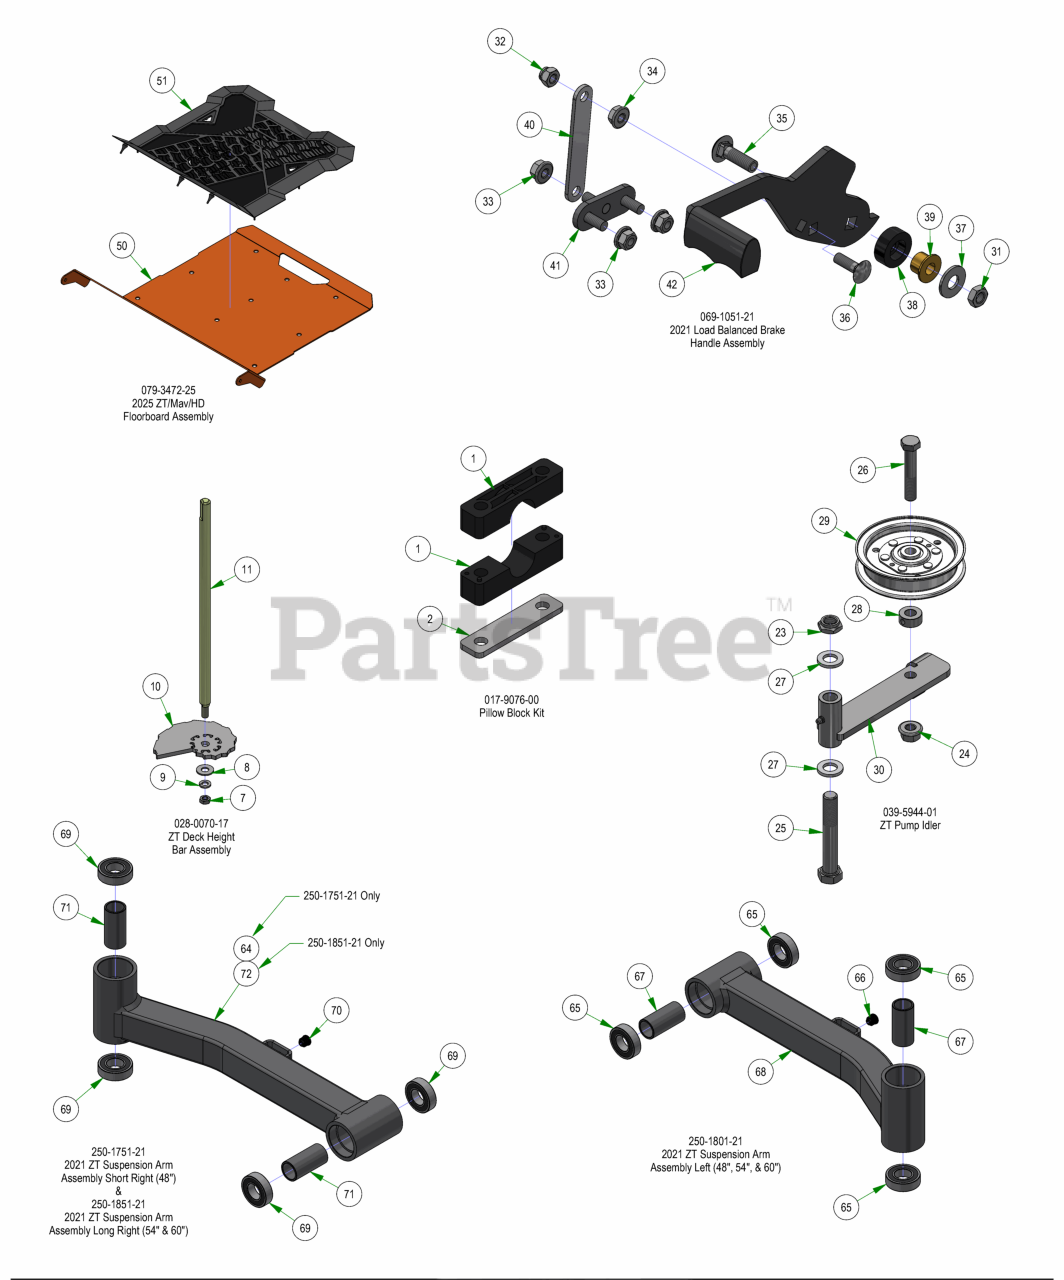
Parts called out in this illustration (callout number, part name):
1	Pillow Block MZ
2	Pillow Block Strap
3	5/16-18 NYLON INSERT FLANGE LOCKNUT ZINC
4	5/16-18 X 1 CARRIAGE BOLT (GR.8) ZINC
5	2017 MZ/ZT Shallow Foot Pedal
6	2017 MZ/ZT Deck Pedal Lever
7	3/8-24 HEX NUT ZINC YELLOW
8	3/8 FLAT WASHER USS (1" OD) ZINC
9	3/8 SPLIT LOCKWASHER ZINC
10	2017 MZ/ZT Cam Plate
11	2017 Deck Height Dial Rod ZT
12	3/8-16 Half Jam Nut
13	3/8-16 HEX SERRATED FLANGE NUT HARD/ZINC
14	3/8-16 X 2 HEX CAP SCREW (GR.5) ZINC
15	3/8 FLAT WASHER USS (1" OD) ZINC
16	Seat Spring
17	3/8-16 Half Jam Nut
18	3/8-16 HEX SERRATED FLANGE NUT HARD/ZINC
19	3/8-16 X 2 HEX CAP SCREW (GR.5) ZINC
20	3/8 FLAT WASHER USS (1" OD) ZINC
21	Seat Spring
22	Seat Strap with Buckles
23	5/8-11 NYLON INSERT JAM LOCKNUT ZINC
24	1/2-13 NYLON INSERT FLANGE LOCKNUT ZINC
25	5/8-11 X 4 HEX CAP SCREW (GR.8) ZINC YELLOW
26	1/2-13 X 2-3/4 HEX CAP SCREW (GR.5) ZINC
27	.635 ID X 1.120 OD X .140 THICK FLAT WASHER NYLON
28	1/2 SOLID SHAFT COLLAR (W/1 SET SCREW) ZINC
29	4 3/4" Idler Pulley
30	Pump Idler Bracket
31	3/8-16 HEX JAM 2-WAY REVERSIBLE CENTER LOCKNUT ZINC
32	5/16-18 NYLON INSERT CAP LOCKNUT ZINC (BLK CAP)
33	5/16-18 NYLON INSERT FLANGE LOCKNUT ZINC
34	5/16-18 HEX SERRATED FLANGE NUT HARD/ZINC
35	3/8-16 X 1-1/4 CARRIAGE BOLT ZINC
36	5/16-18 X 1 CARRIAGE BOLT (GR.8) ZINC
37	3/8 FLAT WASHER USS (1" OD) ZINC
38	2015 Brake Lever Spacer
39	.377 ID X .625 OD X .500 HGT X .880 FLNG DIA X .060 FLNG THK BUSHING
40	Brake Cable Extension Plate
41	Brake Load Balancer Lower Weldment
42	Load Balanced Brake Handle with Grip
43	Black Seat stop from Seat King
44	Seat Cover Molded Foam for 071-2040-18/071-5080-18
45	Back Cover for 071-2101-00
46	Seat Cover for 071-2101-00/071-2102-00
47	Arm rest Kit for 071-2102-00
48	Seat Rails for Outlaw Seat/2020 ZT Elite/ZTAvenger
49	13/14 MZ/Outlaw Seat Switch
50	2025 Elite Maverick Floorboard
51	25 Mav Floor Mat. V4
52	Ignition Switch
53	10-24 NYLON INSERT LOCKNUT ZINC
54	Light Plug
55	10-24 X 5/8 BUTTON SOCKET CAP SCREW 18-8 STAINLESS STEEL
56	Throttle Lever Assembly
57	PTO Engager
58	4-Way Key Switch
59	2022 Maverick HD control panel
60	Tachometer
61	2023 MZ/Magnum/ZT/Maverick Control Panel Decal
62	Relay Block Cover Replacement Kit
64	2021 ZT RH Front Arm - Short
65	1641 BEARING W/2 CONTACT RUBBER SEALS
66	5/8 Round Insert
67	2016 Front Bearing Spacer
68	2021 ZT LH Front Arm
69	1641 BEARING W/2 CONTACT RUBBER SEALS
70	5/8 Round Insert
71	2016 Front Bearing Spacer
72	2021 ZT RH Front Arm - Long
